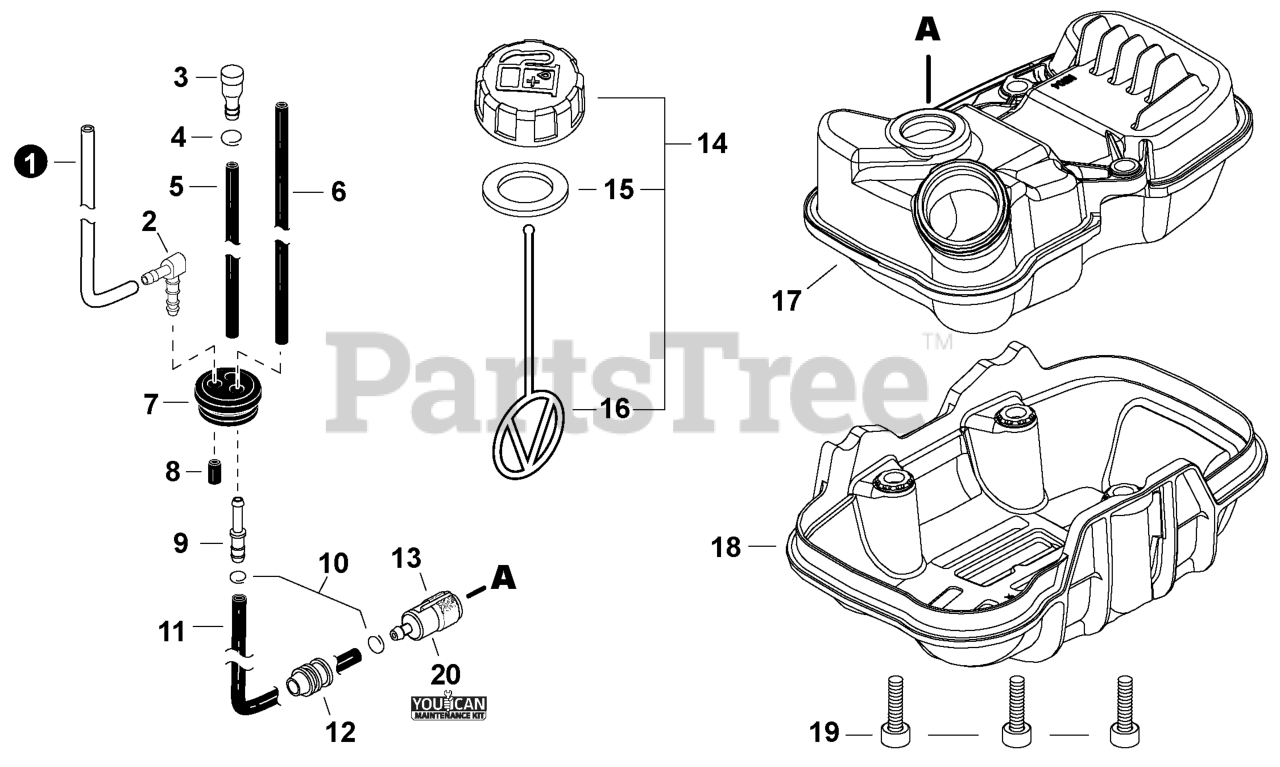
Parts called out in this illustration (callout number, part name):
1	PIPE, FUEL 3x6x75 CLEAR
2	CONNECTOR, PIPE
3	VENT ASSY
4	CLIP 6.5 MM
5	PIPE, FUEL 3x6x85 BLACK
6	PIPE, FUEL 3x5.5x80 BLACK
7	GROMMET, FUEL
8	PIPE, FUEL 3x7x10 BLACK
9	CONNECTOR, PIPE 5x3.5
11	PIPE, FUEL 3x5x115 BLACK
13	FILTER, FUEL
14	CAP ASSY, FUEL
15	GASKET, FUEL CAP
16	CONNECTOR, CAP L= 123
17	TANK, FUEL
18	GUARD, FUEL TANK
19	BOLT 5x20
20	TUNE-UP KIT - YOUCANT
